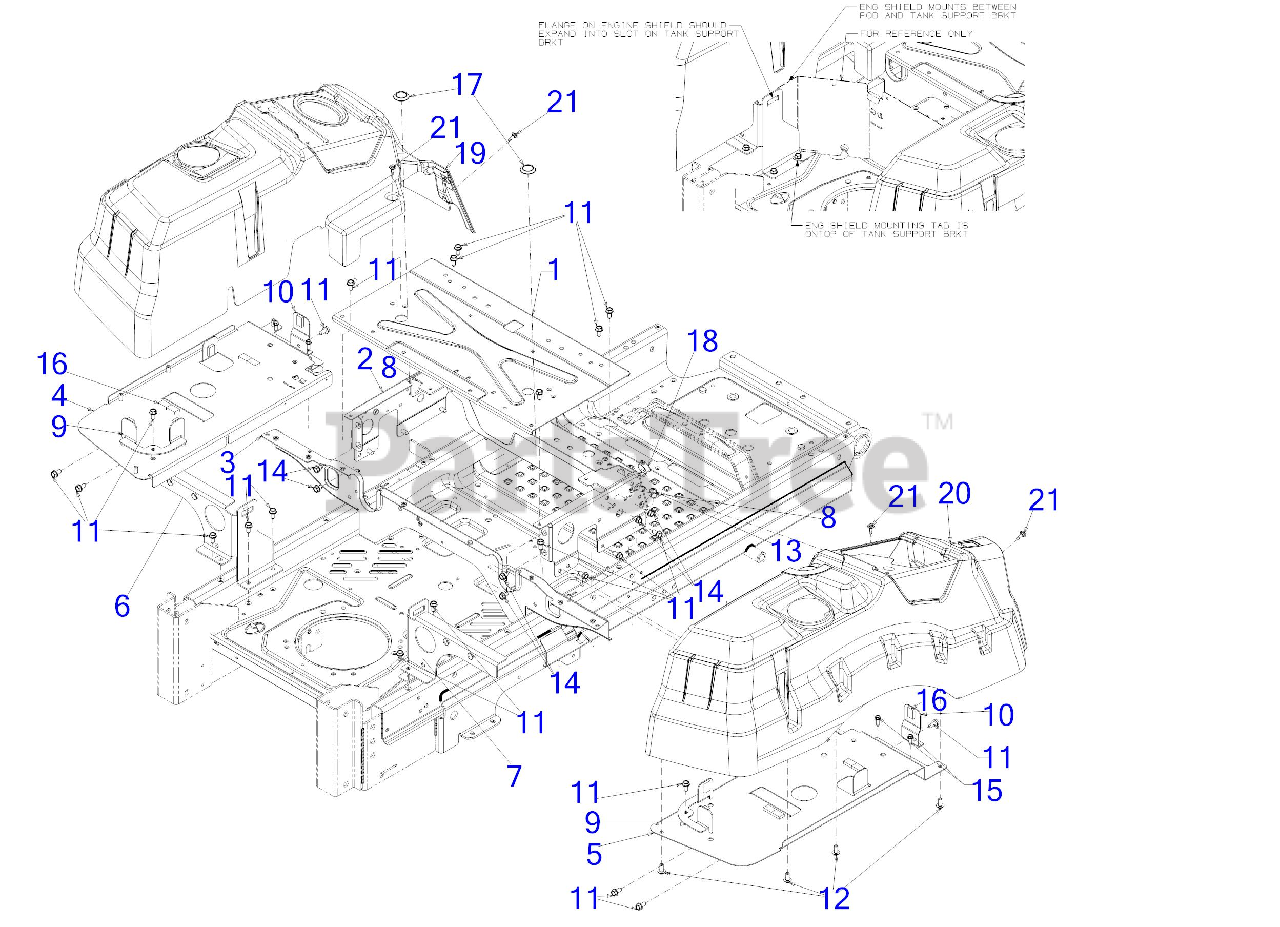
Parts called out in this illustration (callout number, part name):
8	SEAT BOX BRACKET
11	SCREW 5/16-18 x .750
12	SCREW 5/16-14 x .750
13	SCREW 5/16-18 x .750
14	SCREW 5/16-18 x .500
15	SCREW 1/4-20 x .750
16	FOAM TAPE .625 WIDE x .25 THK BULK
18	PLASTIC PLUG
19	CONSOLE (LH) Z-STYLE
20	CONSOLE (RH) Z-STYLE
21	SHOULDER SCREW M6-1 .368 X.115
